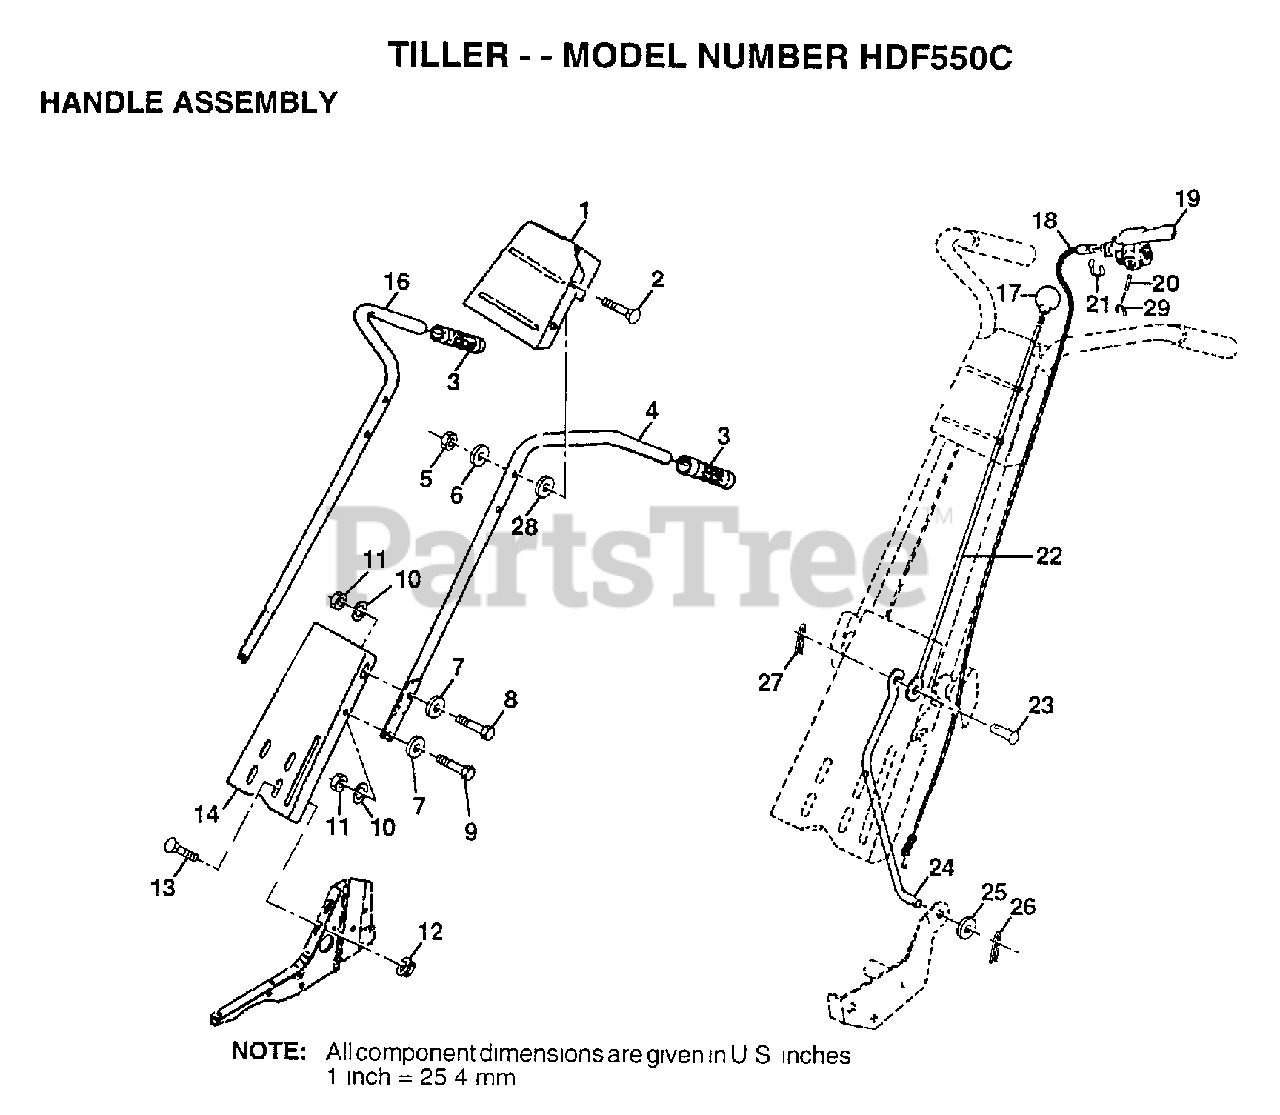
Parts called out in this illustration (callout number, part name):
1	BRACKET.HDLE.TILL
2	BOLT
4	HANDLE.LH TILLER
6	WASHER
7	WASHER
9	BOLT
10	LOCKWASHER
11	NUT.HEX.5/16-18
12	NUT
13	BOLT
14	PANEL.HANDLE.PNT.
16	"HANDLE-RH,TILLER"
17	KNOB T(3/8 HOLE)
18	CABLE CLUTCH T
19	LEVER CONTRL TINE
21	E-RING
22	ROD REVERSE TI
23	RIVET.RD.HD.DRILL
24	REVERSE ROD TI
25	WASHER
26	COTTER PIN
28	WASHER
29	RING
